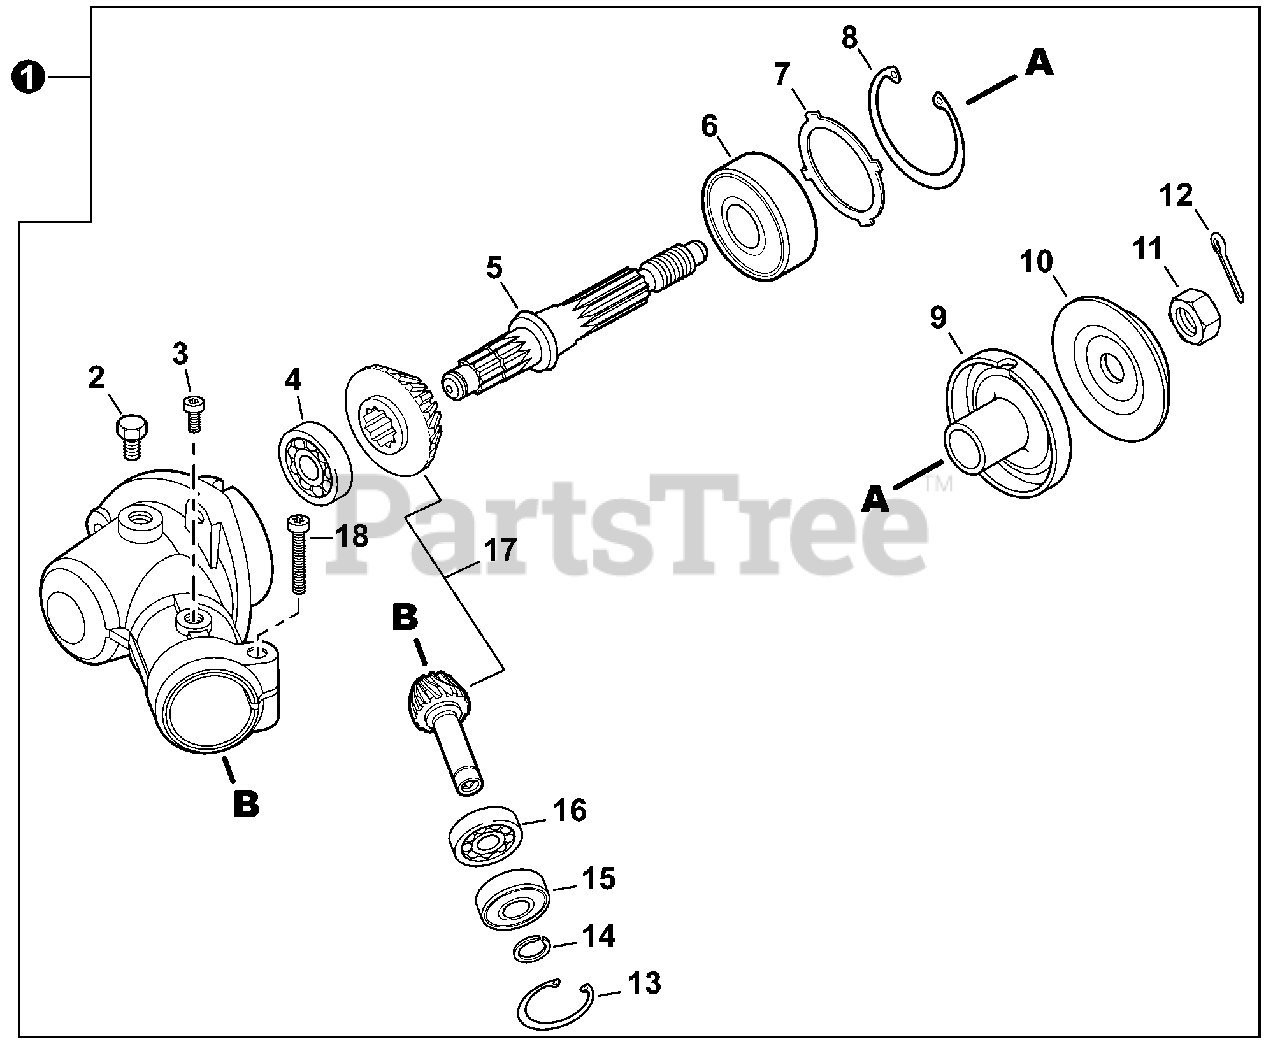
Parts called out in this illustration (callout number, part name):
1	GEAR CASE ASSY
2	BOLT M8×8
3	BOLT, TORX 5×12
4	BEARING, BALL
5	SHAFT, GEAR
6	BEARING, BALL 6201
8	RING, SNAP Ø32
9	PLATE, ADAPTOR - UPPER
10	PLATE, ADAPTOR - LOWER
11	NUT 10×1.25 LH
12	PIN, COTTER 2×22
13	RING, SNAP Ø25
14	RING, SNAP Ø9
15	BEARING, BALL
16	BEARING, BALL
17	GEAR SET
18	BOLT, TORX 5×25
